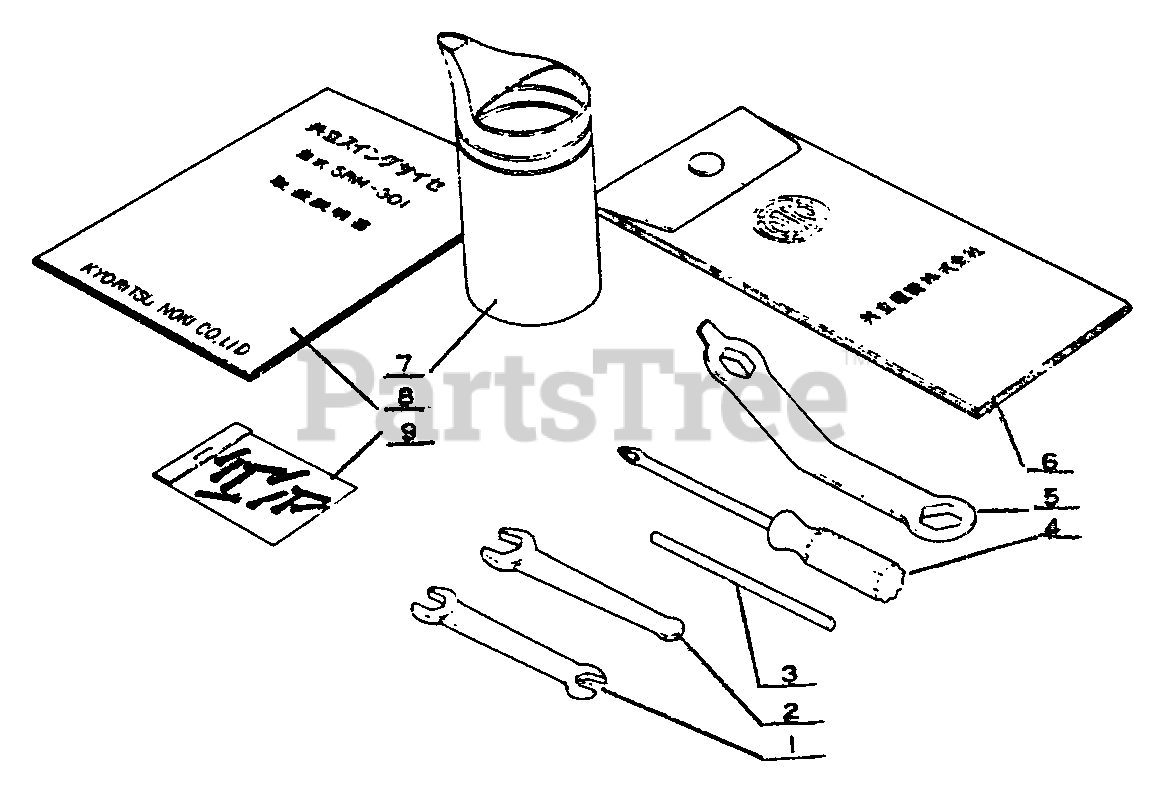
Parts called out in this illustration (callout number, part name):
1	SPANNER - 8×10
2	SPANNER 13
3	FITTING TOOL
4	DRIVER (+)
5	SPANNER 17×18S
6	BAG, TOOL
7	FUEL MIXER
8	OWNER'S MANUAL
10	PIN, COTTER 2×22
